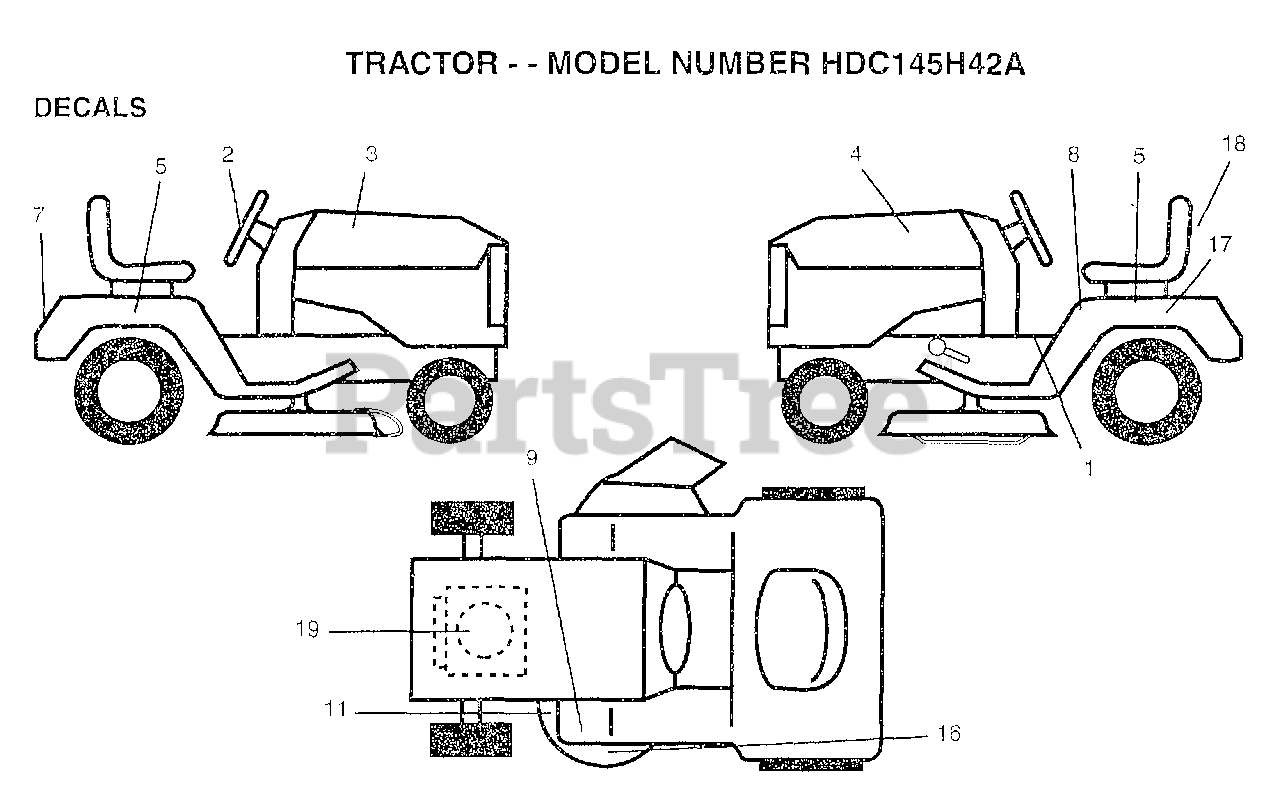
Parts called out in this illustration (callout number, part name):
1	"DECAL-SADDLE,INST"
2	"DECAL WHEEL,STEER"
3	"DECAL-HOOD,RH"
4	"DECAL-HOOD,LH"
5	"DECAL FENDER,SD"
7	"DECAL FENDER,LOGO"
8	"DECAL FENDER,DANG"
9	DECAL CLUT/BRAKE
11	DECAL
16	"DECAL DECK,MULCH"
17	DECAL.BATRY.3-3908
18	"DECAL SEAT,ACC"
19	"DECAL REPLCMT,ENG"
